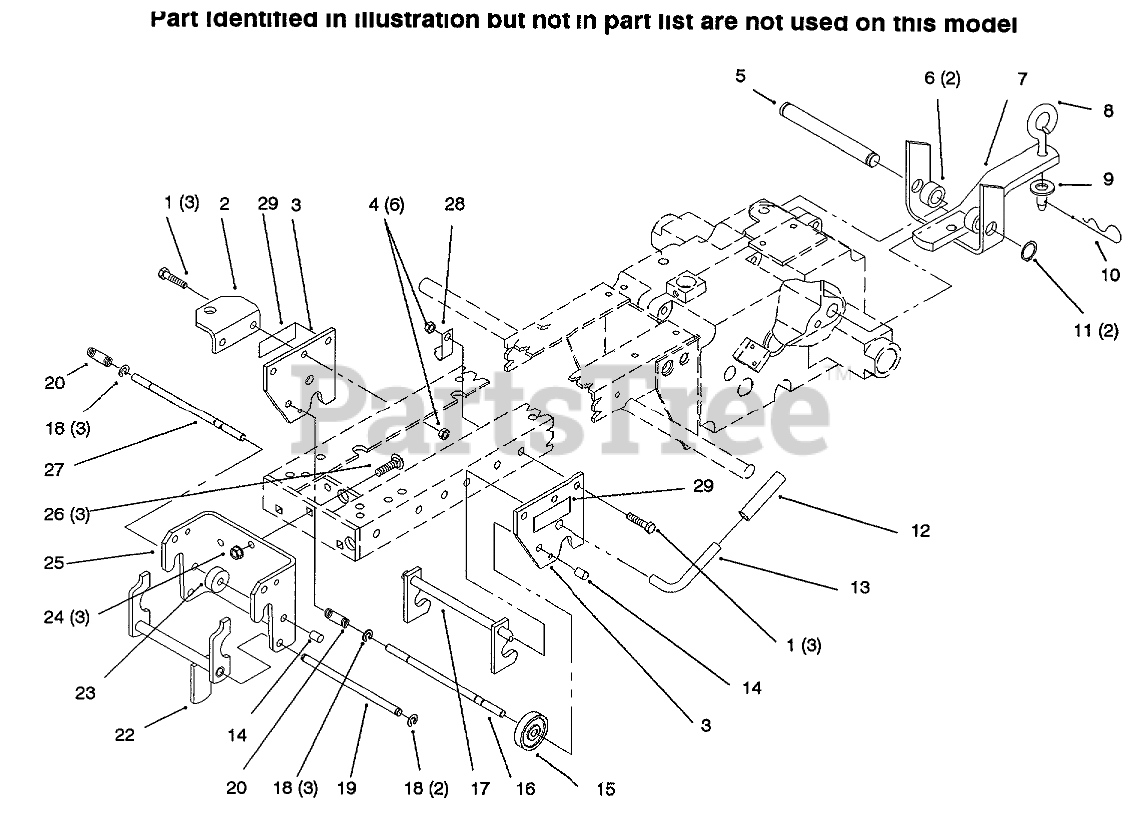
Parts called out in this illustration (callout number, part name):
1	SCREW-HH
3	Hitch Plate
5	PIN-STATIONARY HITCH
6	SPACER
7	Hitch
8	PIN-TOOL
9	WASHER-FLAT
10	PIN-HAIR
11	E-RING
12	GRIP
14	CAP-ROD, PLUNGER
16	ROD-LOCK
17	MID HITCH ASM
18	RING-RETAINING
19	ROD-LATCH PIVOT
20	SPRING
22	LATCH
24	NUT-LOCK, NI
25	Front Hitch
26	BOLT-CARR
27	ROD-LOCK
28	CLIP
29	DECAL - ATTACH-A-MATIC
